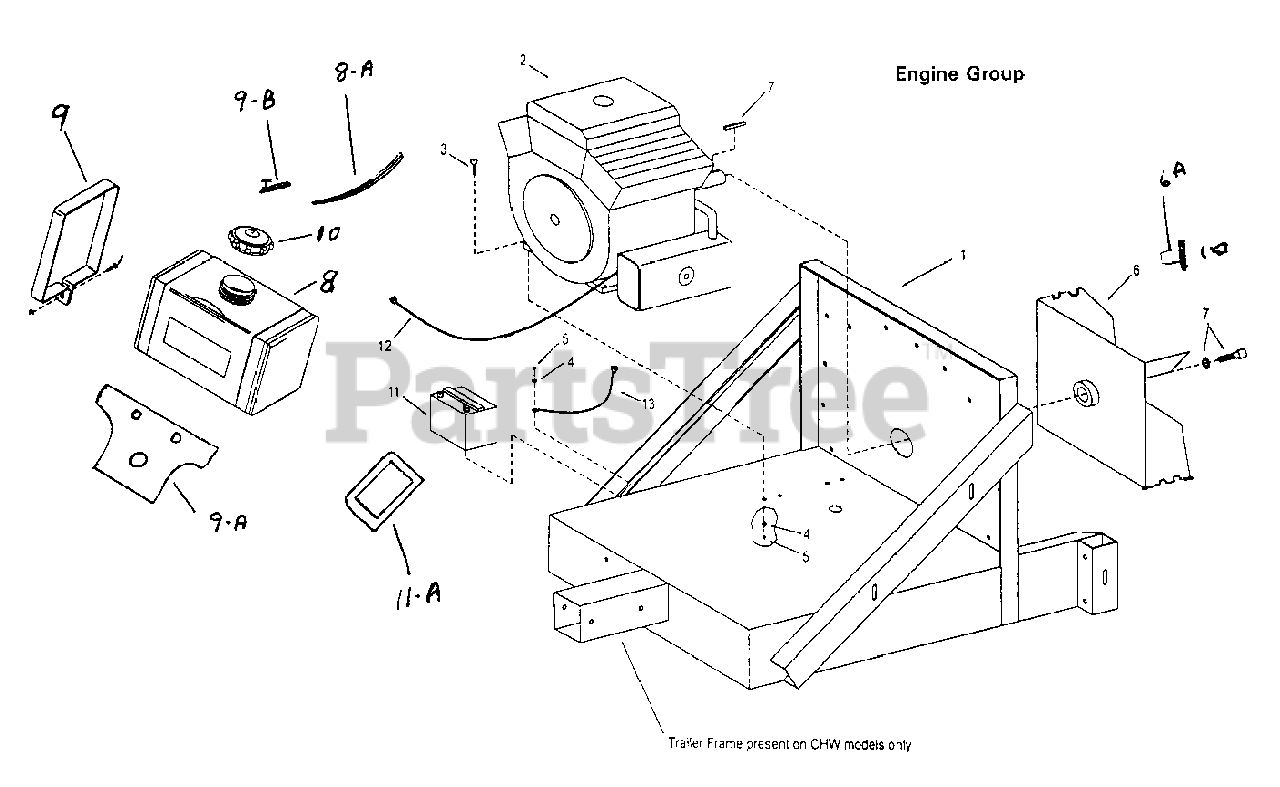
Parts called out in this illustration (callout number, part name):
1	Engine Base SKID Mounts
1	Engine Base & Trailer Frame CHW
2	20HP Kohler Command Engine
2	* Engine, B&S 29HP Mod. 542477-0125-E1
3	3/8 x 2" Hex Bolt (Motor Mount Bolt)
3	3/8 x 1-3/4" Hex Bolt (Motor Mount Bolt)
4	3/8 Lock Washer
5	3/8 Hex Nut
6A	Impeller Hub
7	5/8-18 x 2" Impeller Bolt & Key Group
8	Fuel Tank
8A	Hose, Rubber Fuel 1/4" x 10" Length
9	Fuel Tank Strap
9A	Gas Tank Mount
9B	Inline Fuel Shutoff Valve
10	Fuel Tank Cap
11	Battery, 12 Volt
11A	Battery Box
12	Battery Cable - 32SS (Positive)
13	Battery Cable - 16SS (Ground)
